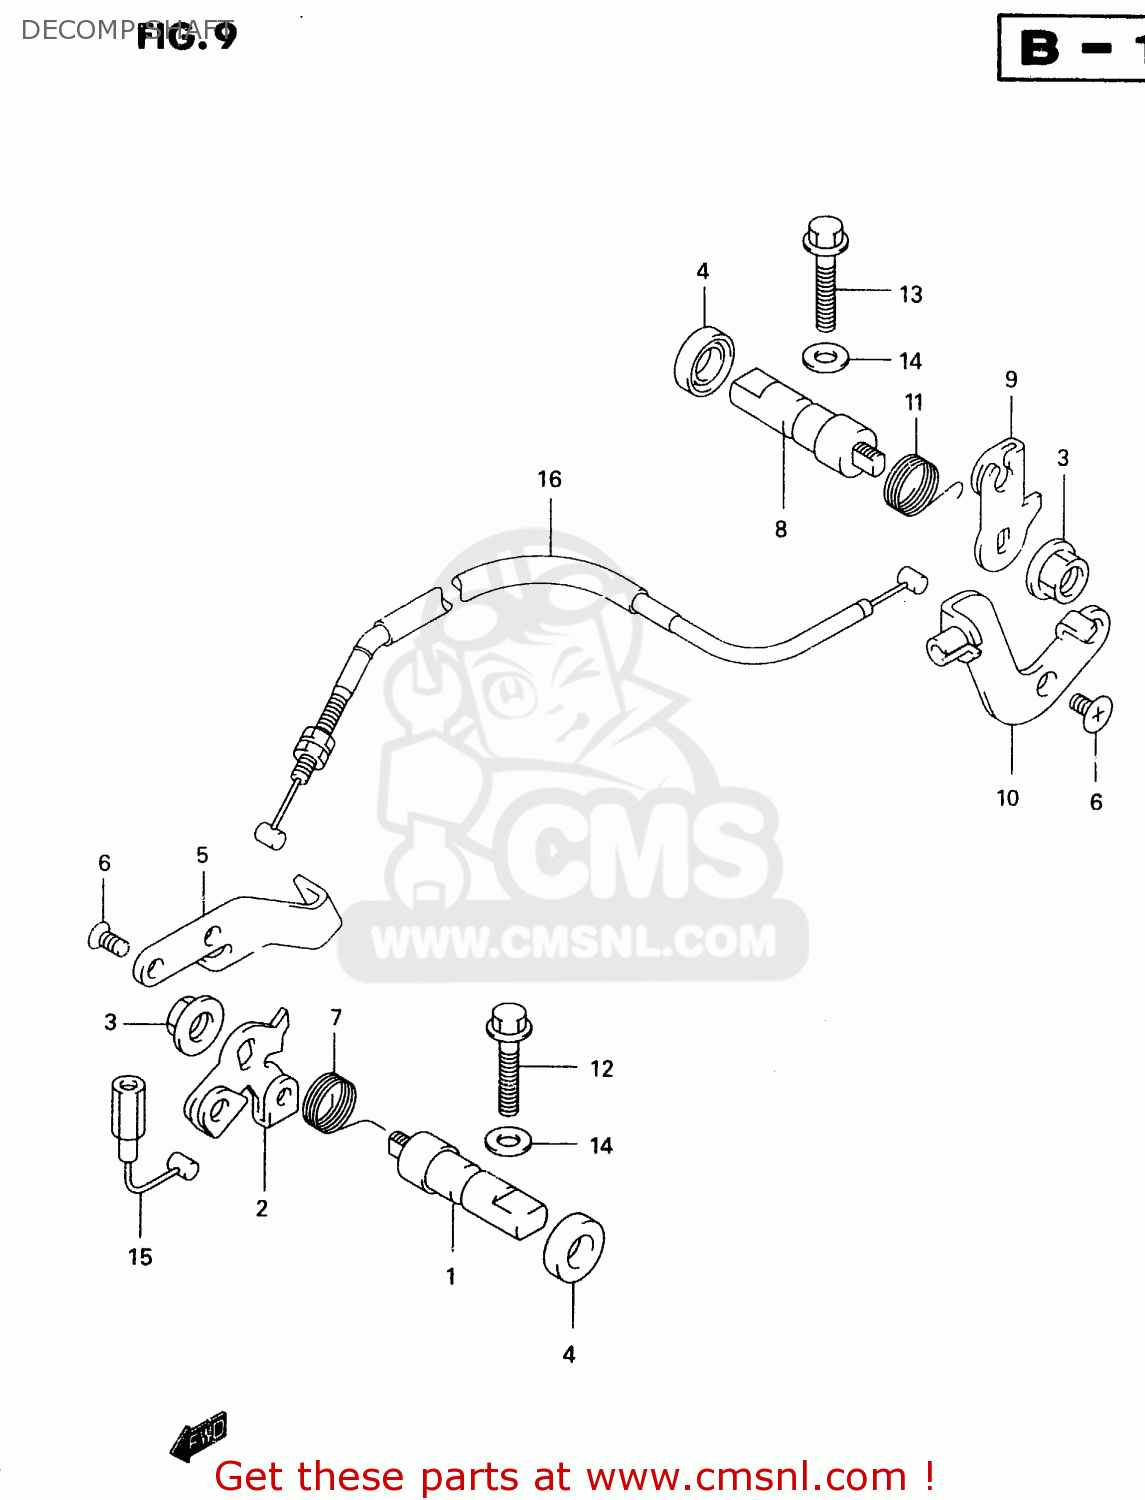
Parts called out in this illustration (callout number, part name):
1	SHAFT,DECOMP FR
2	LEVER,DECOMP SHAFT FR
3	NUT
4	SEAL,OIL(10X20X6)
5	HOLDER,DECOMP CABLE FR
6	SCREW
7	SPRING
8	SHAFT,DECOMP RR
9	LEVER,DECOMP SHAFT RR
10	HOLDER,DECOMP CABLE RR
11	SPRING
12	BOLT
13	BOLT
14	GASKET(5.8X13X1.2) (NAS)
15	CABLE ASSY,DECOMP FR
16	CABLE ASSEMBLY,DECOMPRESSION,REAR
